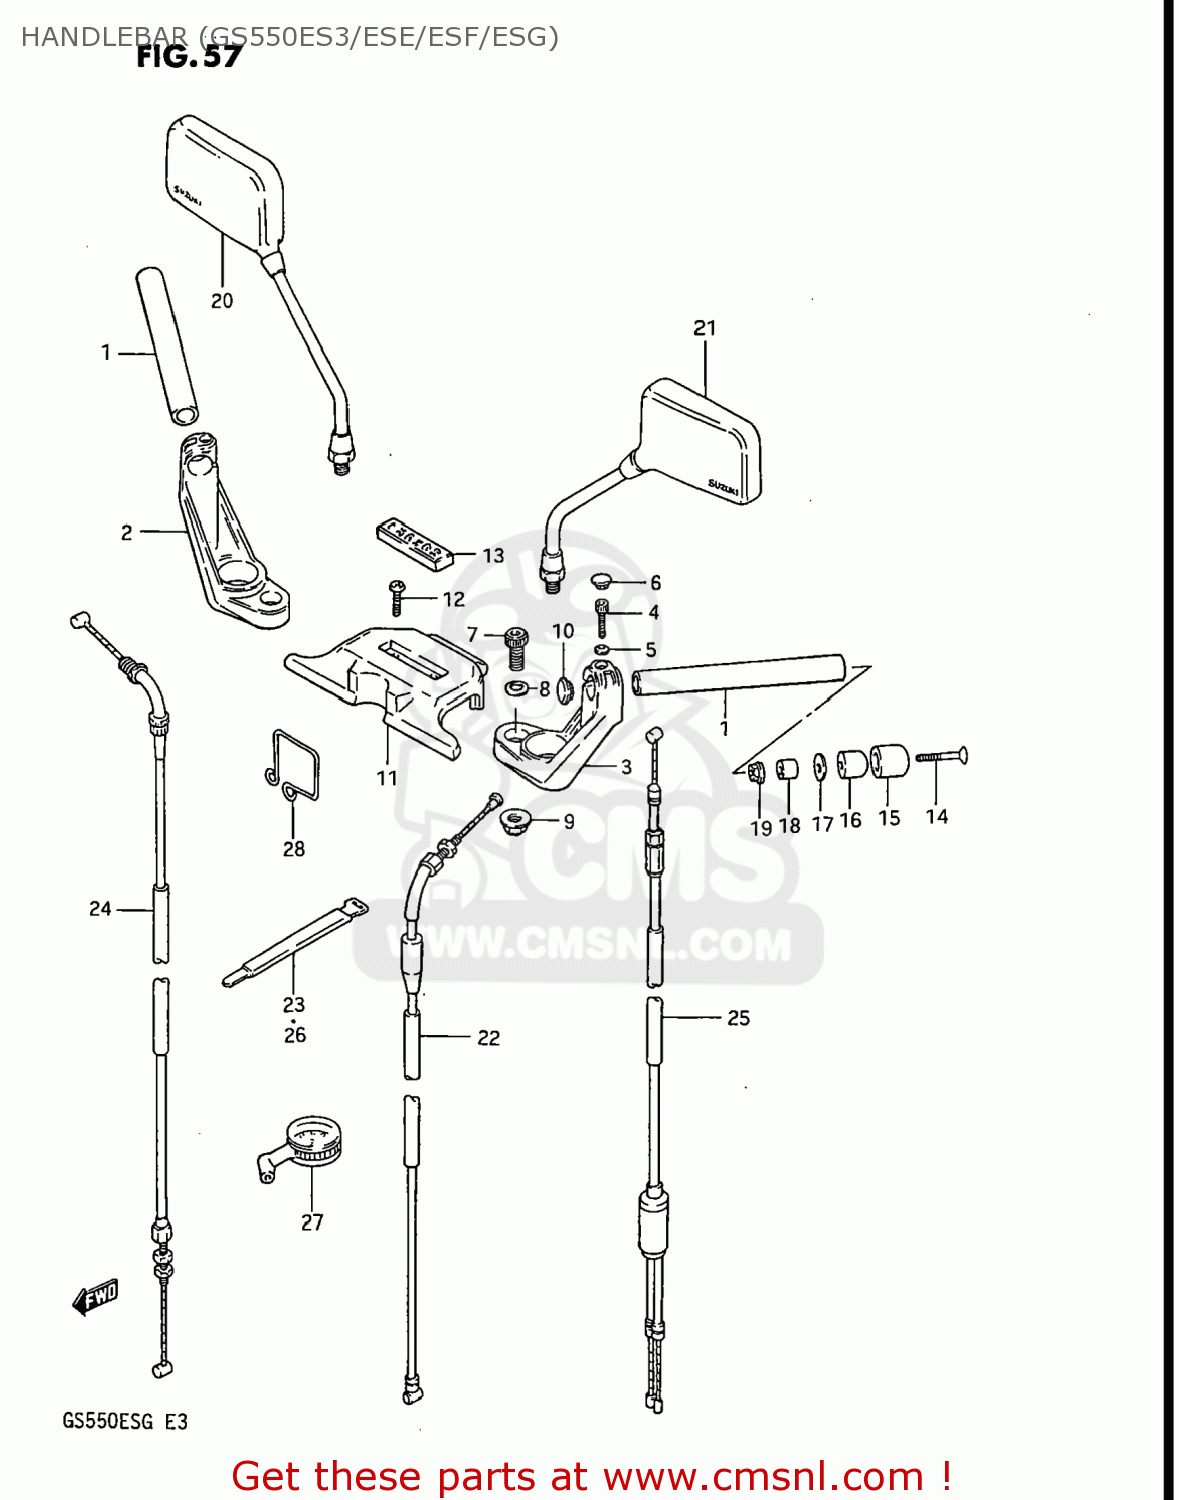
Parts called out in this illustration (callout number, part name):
1	HANDLEBAR
2	HOLDER,HANDLEBAR,RIGHT
3	HOLDER,HANDLEBAR,LEFT
4	BOLT 8X35
5	WASHER
6	CAP(OD:14.5)
7	BOLT(10X50)
8	WASHER
9	NUT
10	CAP,GRIP END
11	PAD,HANDLEBAR
12	SCREW
13	EMBLEM,HANDLE PAD
14	SCREW 6X55
15	CAP,BALANCER
16	BALANCER,HANDLEBAR
17	SPACER,BALANCER
18	EXPANDER,BALANCER
19	NUT
20	MIRROR ASSEMBLY,REAR VIEW
21	MIRROR ASSEMBLY,REAR VIEW
22	CABLE ASSY,CLUTCH
23	CLAMP
24	CABLE ASSY,THROTTLE
25	CABLE COMP,STARTER
26	CLAMP
27	GAUGE ASSY,AIR PRESSURE
28	GUIDE,CABLE/HARNESS
